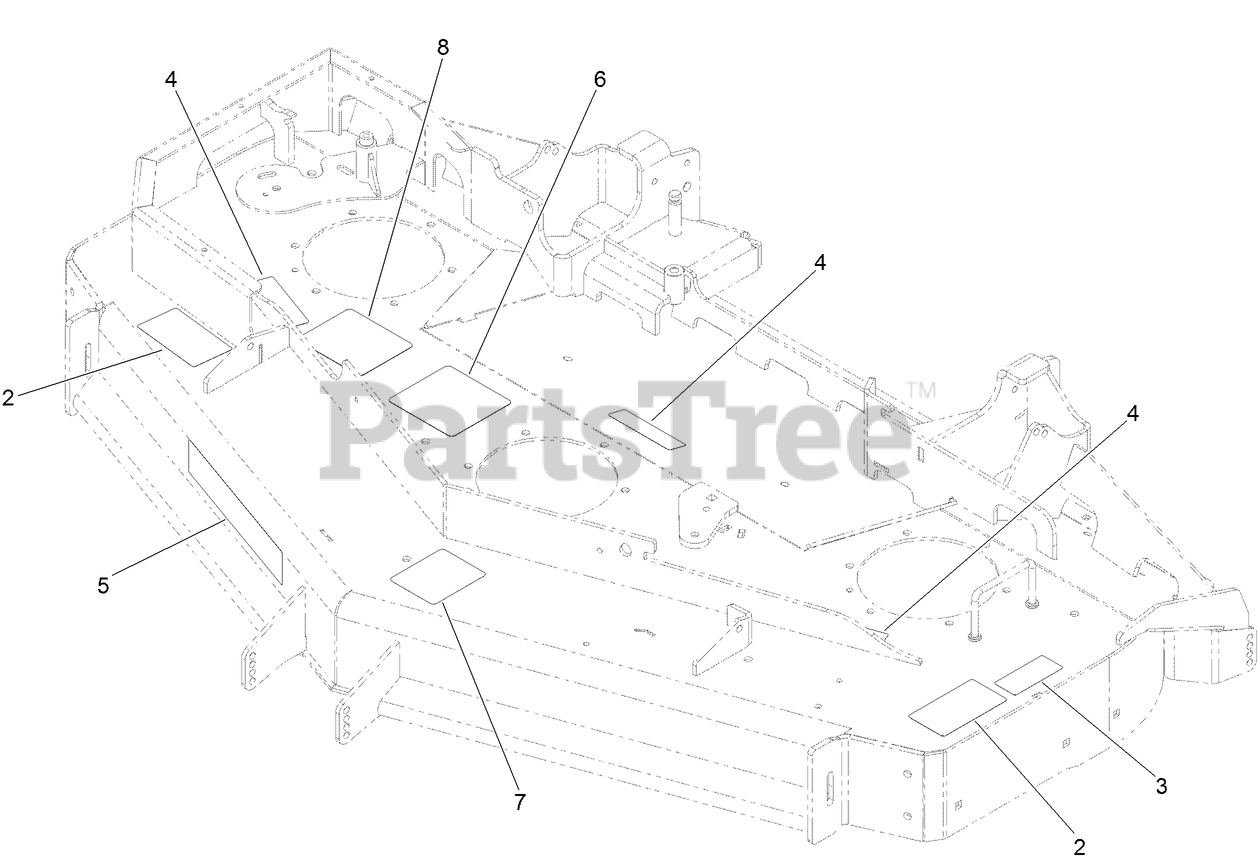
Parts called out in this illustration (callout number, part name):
2	DECAL-DANGER
3	DECAL-BOLT TORQUE
4	DECAL-COVER, MISSING
6	DECAL-ROUTING, DECK BELT
7	DECAL-ROLLER, ANTI-SCALP
8	DECAL-SPINDLE CR, CE
